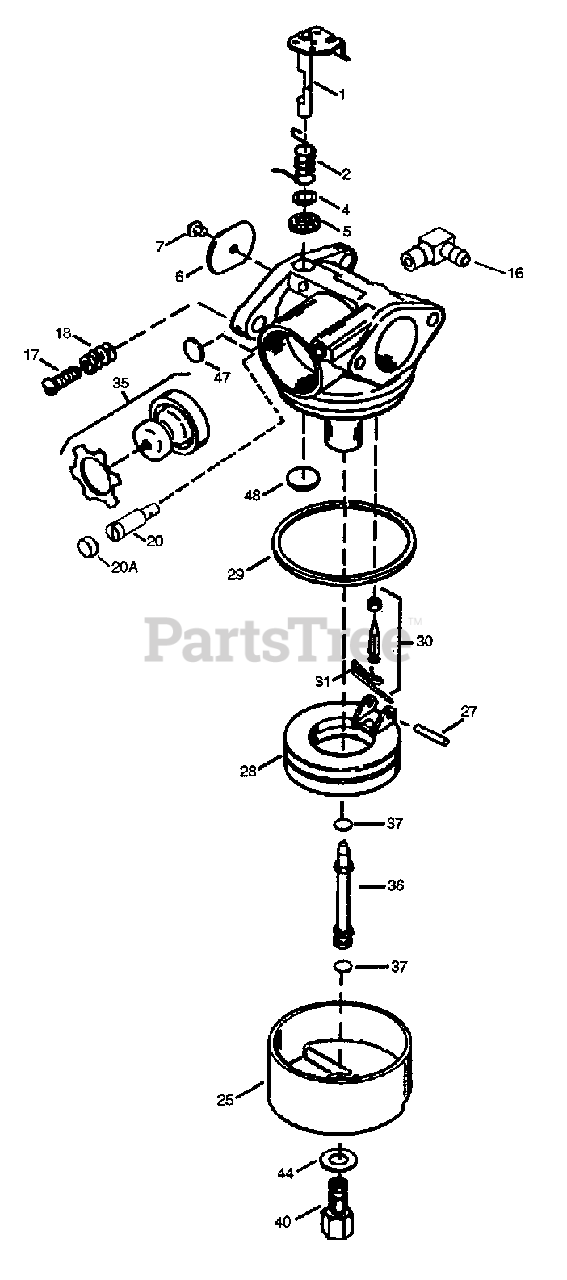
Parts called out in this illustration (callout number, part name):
1	Throttle Shaft & Lever Assembly
2	Throttle Return Spring
4	Dust Seal Washer
5	Dust Seal (Throttle)
6	Throttle Shutter
7	Shutter Screw
16	Fuel Fitting
17	Throttle Crack Screw/Idle Speed Screw
18	Tension Spring
20	Idle Restrictor Screw
20A	Idle Restrictor Screw Cap
25	Float Bowl
27	Float Shaft
29	Float Bowl "O" Ring
30	Inlet Needle, Seat, & Clip (Incl. 31)
31	Spring Clip
35	Primer Bulb/Retainer Ring
36	Main Nozzle Tube
37	O-Ring, Main Nozzle Tube
40	High Speed Bowl Nut
44	Bowl Nut Washer
47	Welch Plug, Idle Mixture Well
48	Welch Plug, Atmospheric Vent
